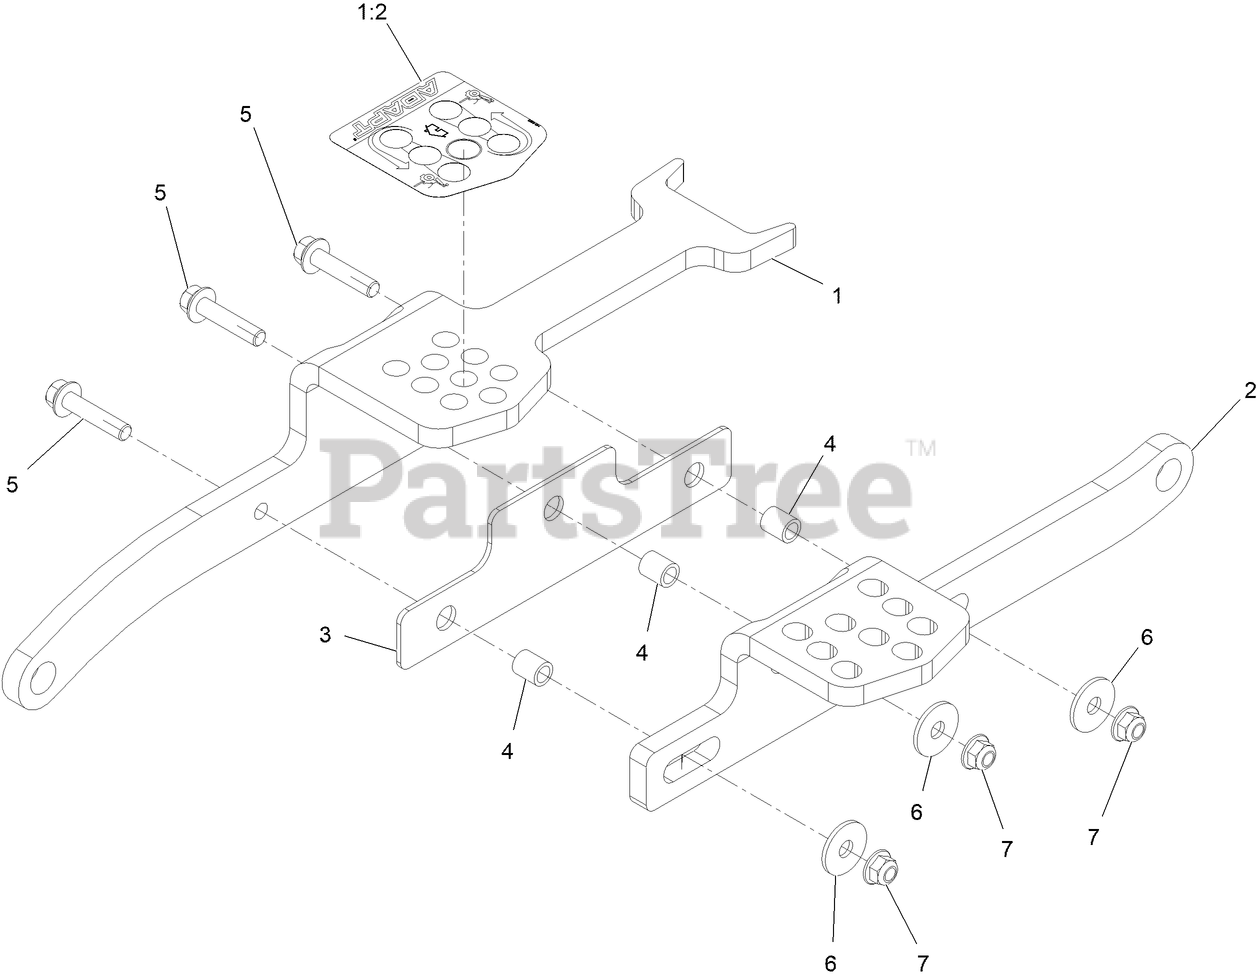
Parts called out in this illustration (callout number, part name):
1	ASM- Link W/Decal
1:2	Decal- Rake
2	Link- Deck Lift Rear
3	PLATE- SLIDE
4	Spacer- Short
5	SCREW-HHF
6	WASHER-HARDENED
7	NUT-HF, NI
